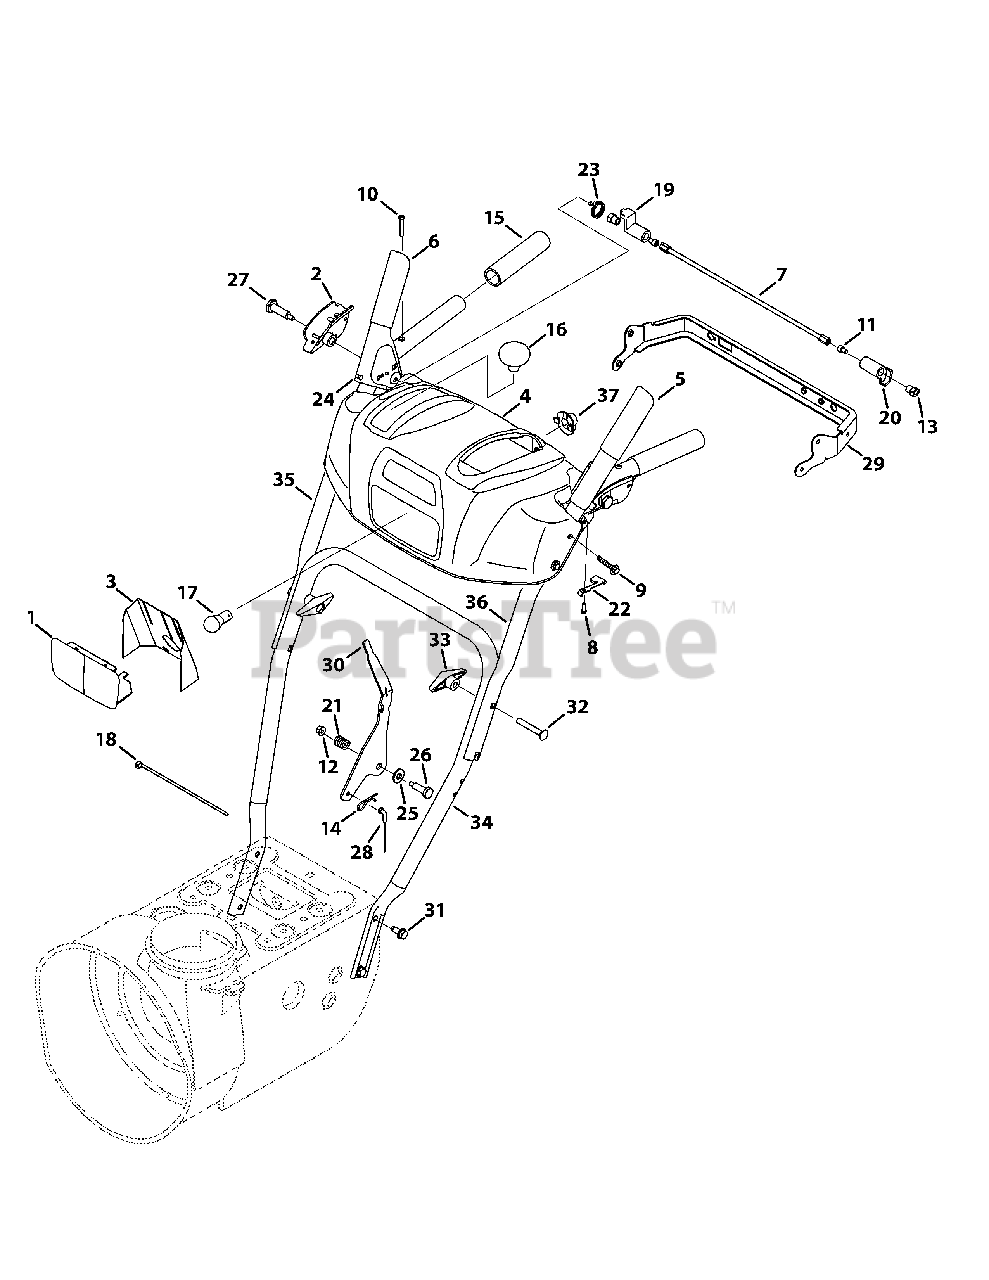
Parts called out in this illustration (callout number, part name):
2	Handle Clutch Lock - RH
2	Handle Clutch Lock - LH
3	Lens Reflector Label
4	T-Style Panel Ass’y, (inc. Ref. 1 & 3)
5	Handle Engagement Assembly LH
6	Handle Engagement Assembly RH
8	Screw, Plastite, 8-16 x .50
9	Screw, 1/4-20 x 1.625
10	Screw, #10-24 x 1.375
11	Screw, Socket, 1/4-20 x .50
12	Flange Lock Nut, 1/4-20
13	Shoulder Nut, 1/4-20
14	Click Pin
15	Handle Grip
16	Shift Knob
17	Lamp - #1683
18	Cable Tie
20	Clutch Lock Cam
21	Compression Spring
22	Clutch Lock Spring
23	Torsion Spring
24	Rubber Bumper
25	Flat Washer, .385 x .87 x .06
26	Shoulder Screw, .374 x 1.05
27	Shoulder Screw, 1/4-20 x 1.345
28	Speed Selector Cable
31	Screw, 5/16-18 x .750
32	Carriage Screw, 5/16-18 x 2.25
33	Wing Knob
37	Light Socket
